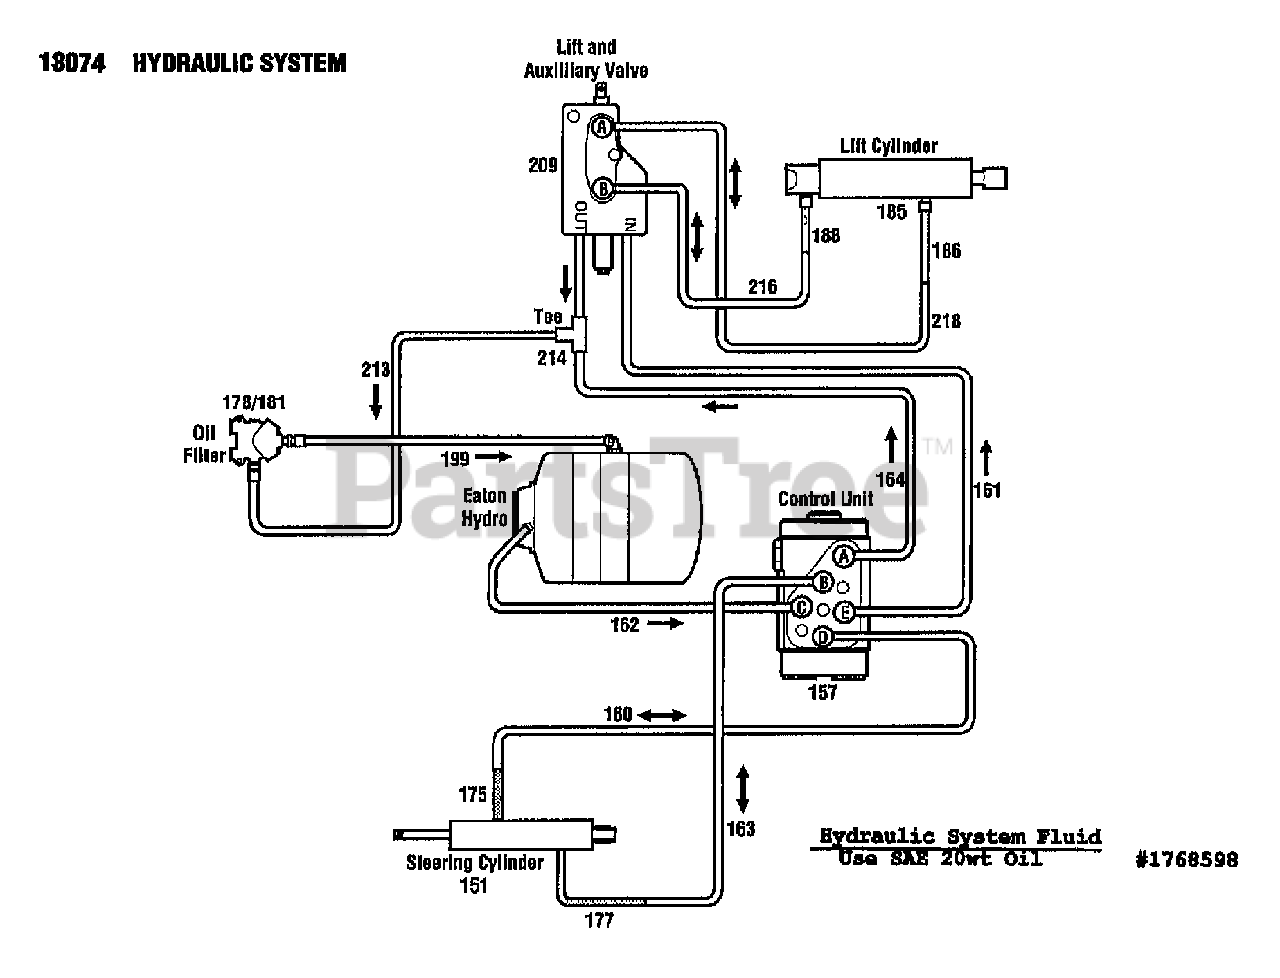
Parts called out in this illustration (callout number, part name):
151	CYLINDER-HYDRAULIC
157	CONTROL UNIT
160	TUBE-HYD RIGHT
161	TUBE-HYD PB VALVE
162	TUBE-HYDRO PRESSURE
163	TUBE-HYD LEFT
164	TUBE-HYD S C U TANK
175	ASSM-HOSE
177	ASSM-HOSE
178	FILTER-OIL
181	MANIFOLD-FILTER
185	ASSM-CYL HYDRAULIC
186	ASSM-HOSE
188	ASSM-HOSE
199	ASSM-RETURN TUBE
209	VALVE-HYDRAULIC
213	TUBE-HYD RETURN
214	TEE-SWIVEL
216	TUBE-HYD VALVE TO ROD
218	TUBE-HYD VALVE TO HEAD
